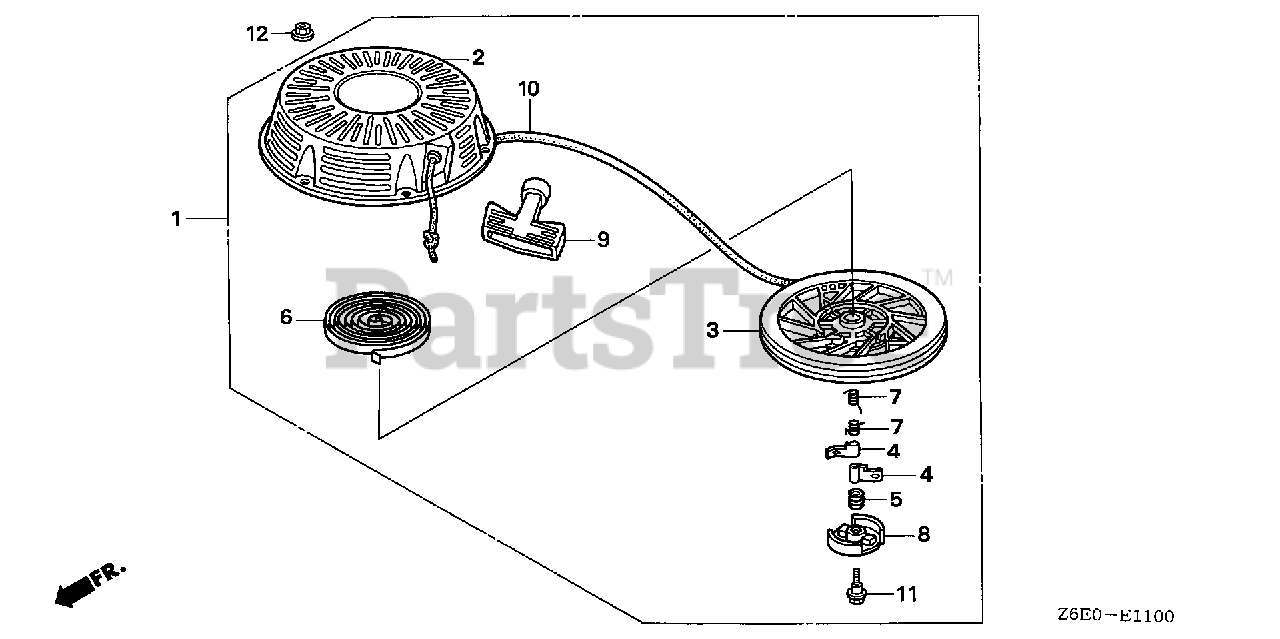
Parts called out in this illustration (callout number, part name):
1	STARTER ASSY., RECOIL *R280* (POWER RED)
2	CASE, RECOIL STARTER *R280* (POWER RED)
3	PULLEY, RECOIL STARTER
4	RATCHET, STARTER
5	SPRING, FRICTION
6	SPRING, STARTER RETURN
7	SPRING, RATCHET
8	RETAINER, SPRING
9	GRIP, STARTER
10	ROPE, RECOIL STARTER
11	SCREW, CENTER
12	NUT, FLANGE (6MM)
